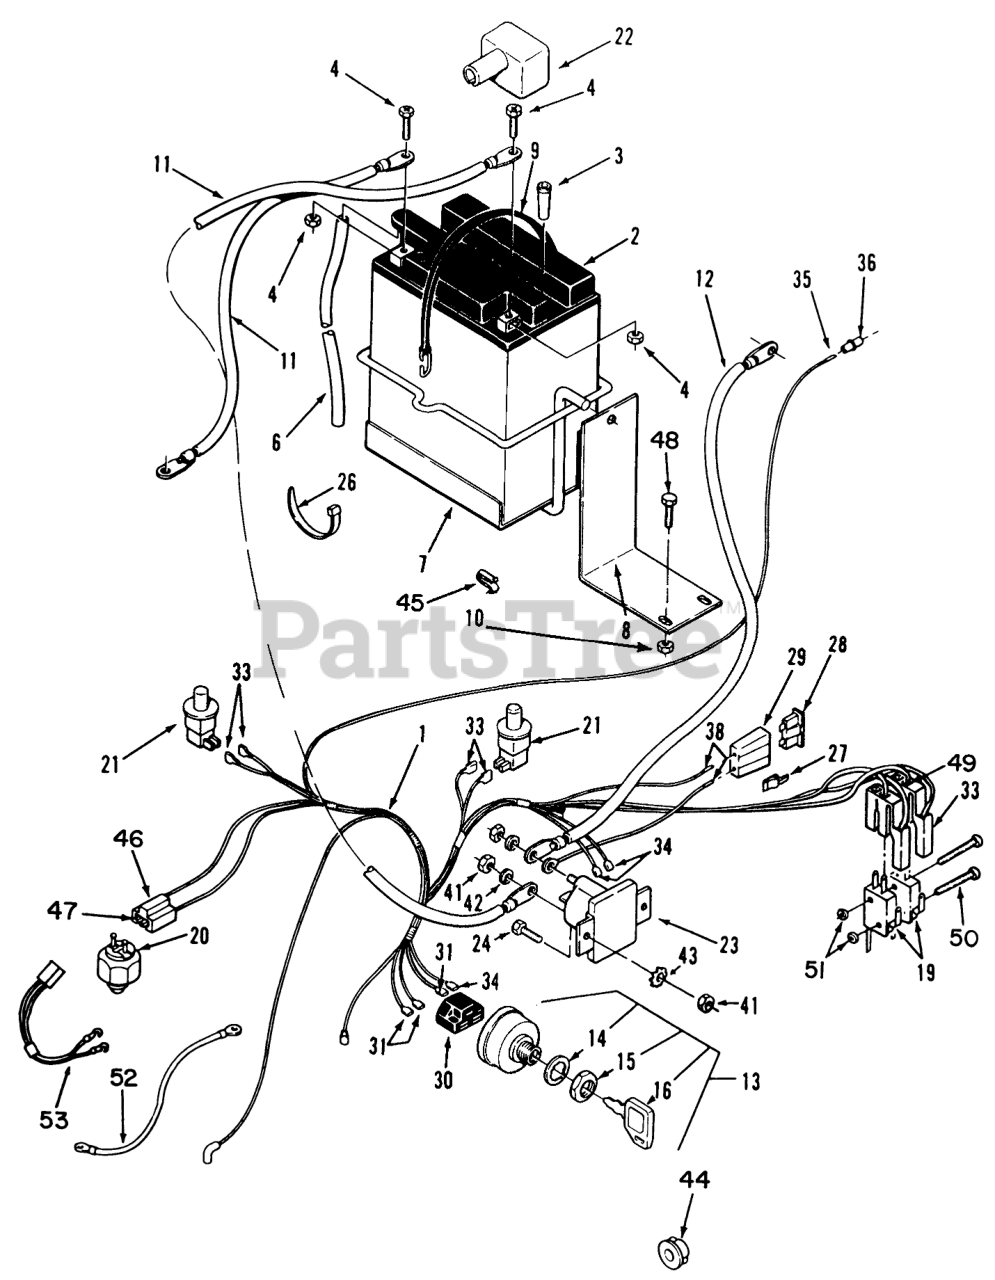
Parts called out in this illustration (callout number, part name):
1	Harness-Wiring (Includes Ref. #30-39, 46, & 47)
2	BATTERY 120CCA
3	ADAPTER
4	ASSY BATTERY HDW
6	HOSE BATTERY DRAIN
7	BATTERY TRAY B
8	BRACKET B
9	STRAP
10	NUT-HEX
11	ASSY WIRE
12	WIRE ASM
13	Switch-Ignition (Incl. Ref. #14 & 15)
14	LOCKWASHER
16	KEY-IGNITION
19	SWITCH-LEVER
20	SWITCH (N.C.-TRANS)
21	SWITCH (N.C.)
22	COVER-TERMINAL
23	Solenoid
24	Bolt-Whizlock
26	PLASTIC TIE
28	FUSE-BLADE, 15 AMP
29	AUTO-FUSEBLOCK TERM
30	CONNECTOR-5 WAY-SERV
31	Terminal-Wire
33	Terminal-Wire
34	TERMINAL-TAB RCPT
35	Terminal
36	SOCKET HOUSING
39	TERMINAL FUSE
41	NUT-HEX
42	WASHER-LOCK
43	WASHER-LOCK/EXT
44	BUSHING-NYLON 1.093
45	CLIP
46	CONNECTOR BODY
47	TERMINAL-LONG MALE
48	SCREW-HH
49	CONNECTOR BODY
50	Screw
51	NUT HEX 4-40 ELAST
52	WIRE-BONDING
53	ASSY WIRING HARNESS
